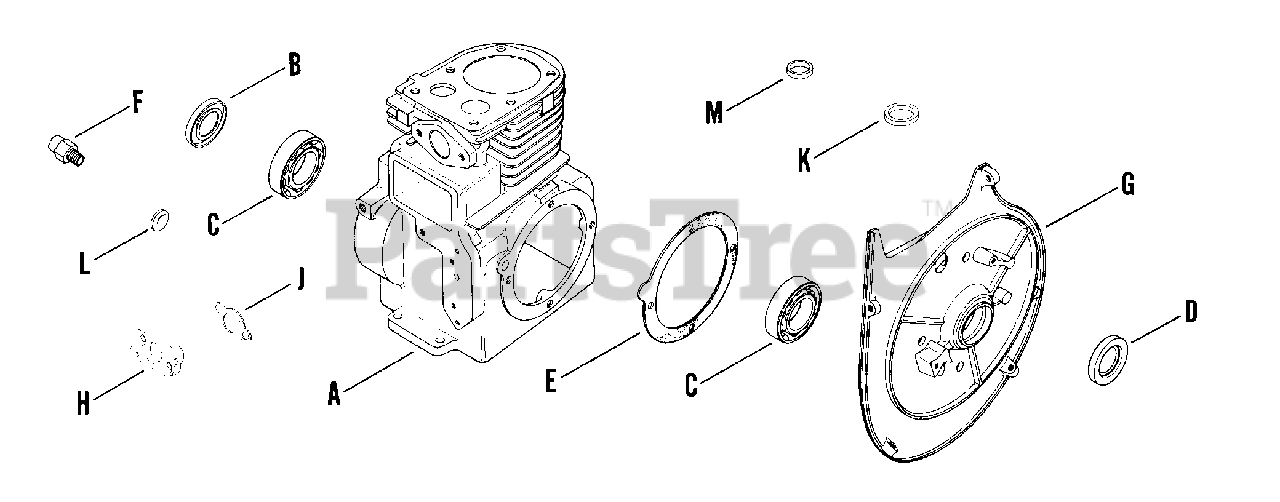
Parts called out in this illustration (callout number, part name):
B	SEAL - USE X-271-16
C	BEARING - DISCONTINUED
D	SEAL - USE X-271-15
